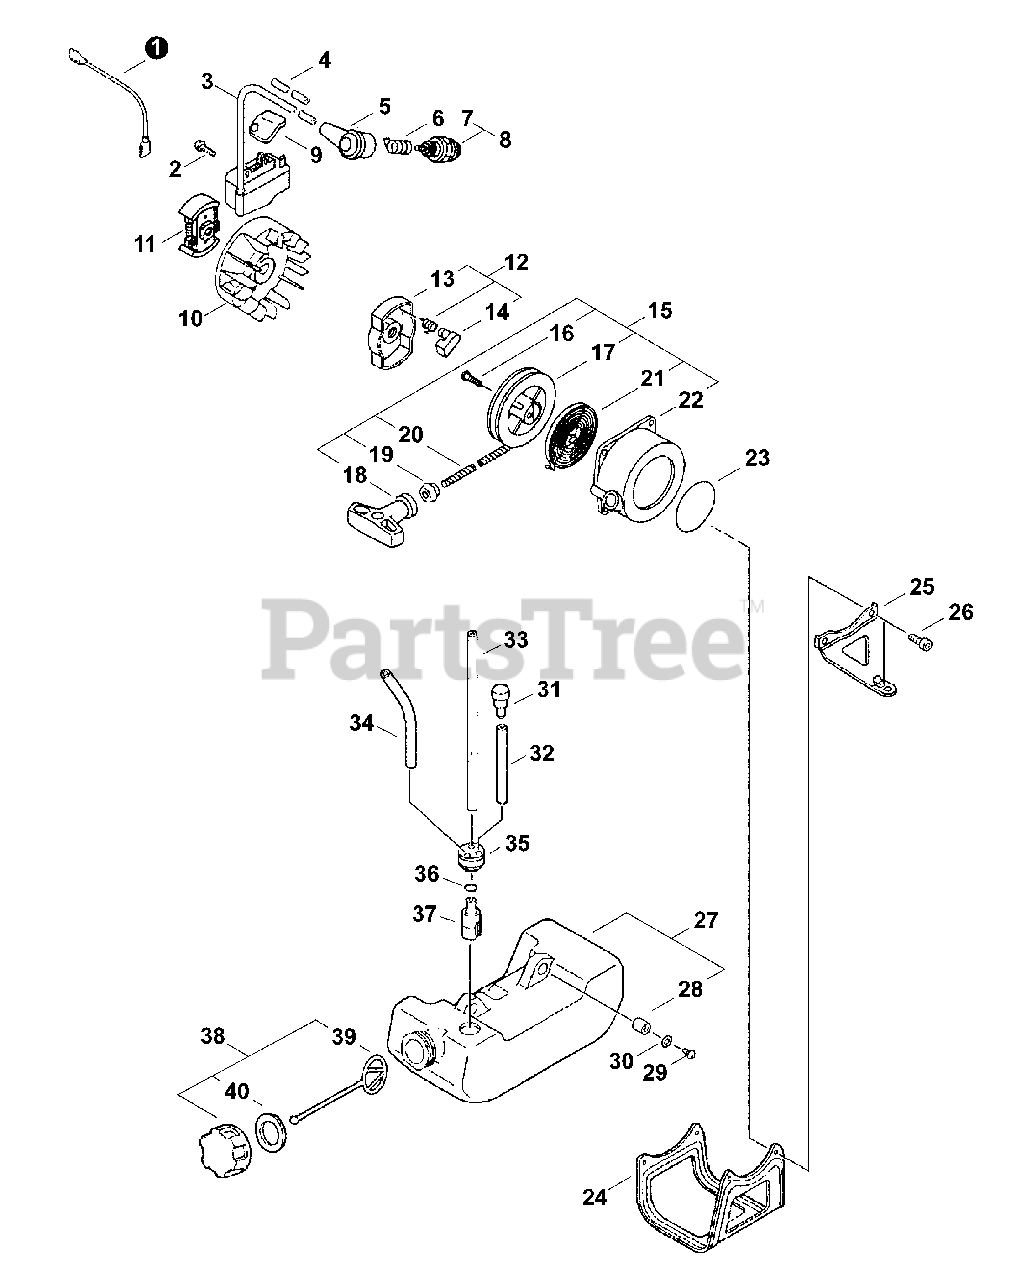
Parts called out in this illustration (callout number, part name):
1	LEAD - IGNITION
2	SCREW - 4×20
3	COIL, IGNITION
4	TUBE, INSULATOR
5	CAP, SPARK PLUG
6	TERMINAL, SPARK PLUG CAP
7	SPARK PLUG -- BPM8Y
8	SPARK PLUG -- BPMR8Y
9	COVER, DUST
10	FLYWHEEL
11	CLUTCH ASSY
12	STARTER PAWL ASSY
13	SPRING, RETURN
14	PAWL, STARTER
15	STARTER ASSY
17	REEL, ROPE
18	GRIP, STARTER
19	GUIDE, ROPE
20	ROPE, STARTER - 3×1000
21	SPRING, REWIND
22	CASE, STARTER
23	LABEL - ECHO
24	GUARD, FUEL TANK
25	SUPPORT, REAR HANDLE
26	SCREW - 4×16
27	TANK, FUEL
29	SCREW - 5×16
30	WASHER - 5
31	VENT, FUEL TANK
32	PIPE - 3×5×30 -- BLACK
33	PIPE - 3×5×160 -- BLACK
34	PIPE - 3×6×80 -- CLEAR
36	CLIP - 6
37	FILTER, FUEL
38	CAP ASSY - ORANGE
39	CONNECTOR, CAP
40	GASKET, CAP
